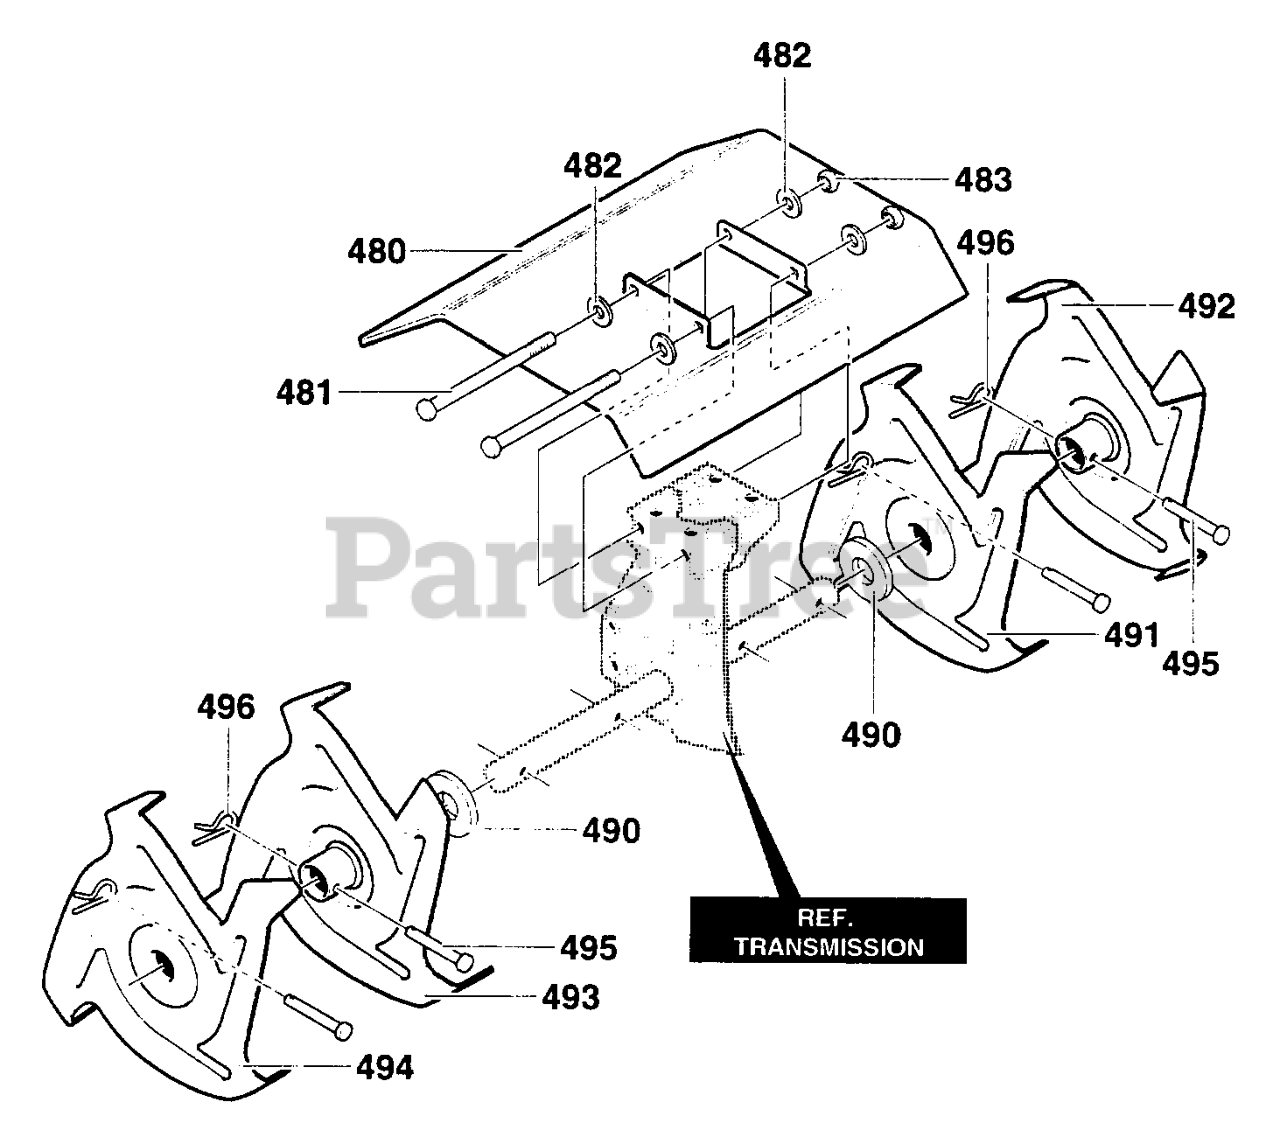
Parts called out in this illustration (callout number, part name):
480	Shield, Tine
481	Screw, 1/4-20x5.50
482	Spacer, Flange
483	Nut, 1/4-20
490	Washer, Felt
491	Tine Assy. Inner LH
492	Tine Assy. Outer LH
493	Tine Assy. Inner RH
494	Tine Assy. Outer RH
495	Clevis Pin
